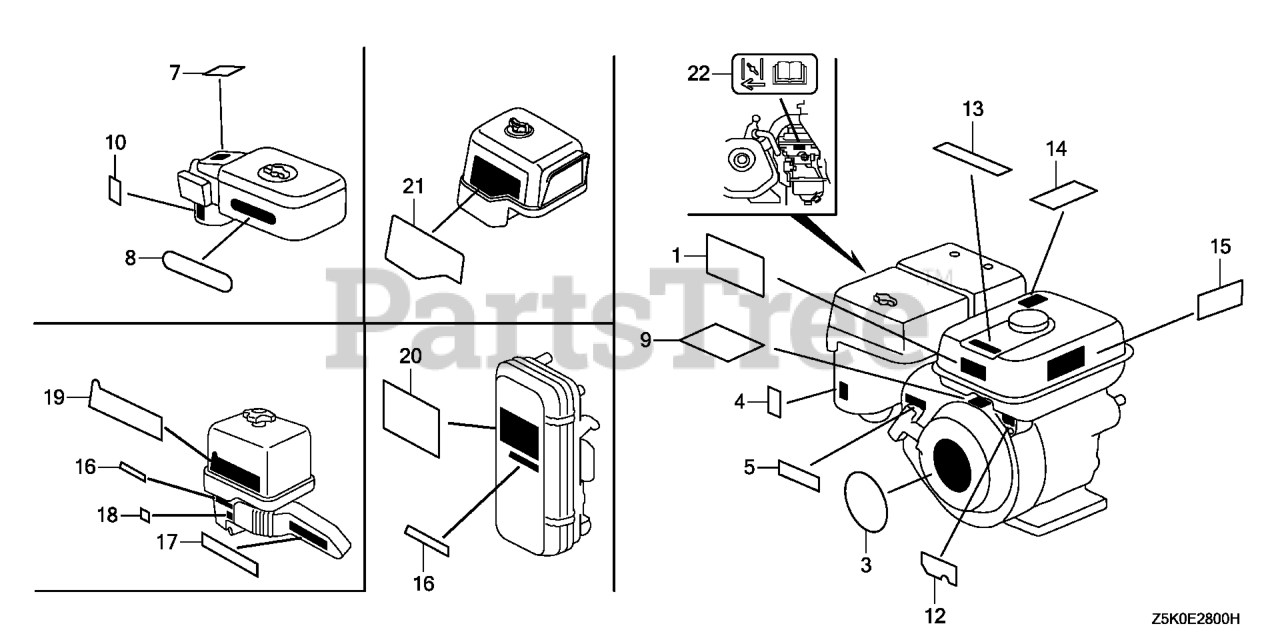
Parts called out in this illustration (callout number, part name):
3	EMBLEM (GX270)
4	MARK, CHOKE
5	MARK, THROTTLE INDICATION
14	MARK, EX. CAUTION (ENGLISH)
15	MARK, OPERATOR CAUTION (ENGLISH)(MADE IN THAI)
15	MARK
